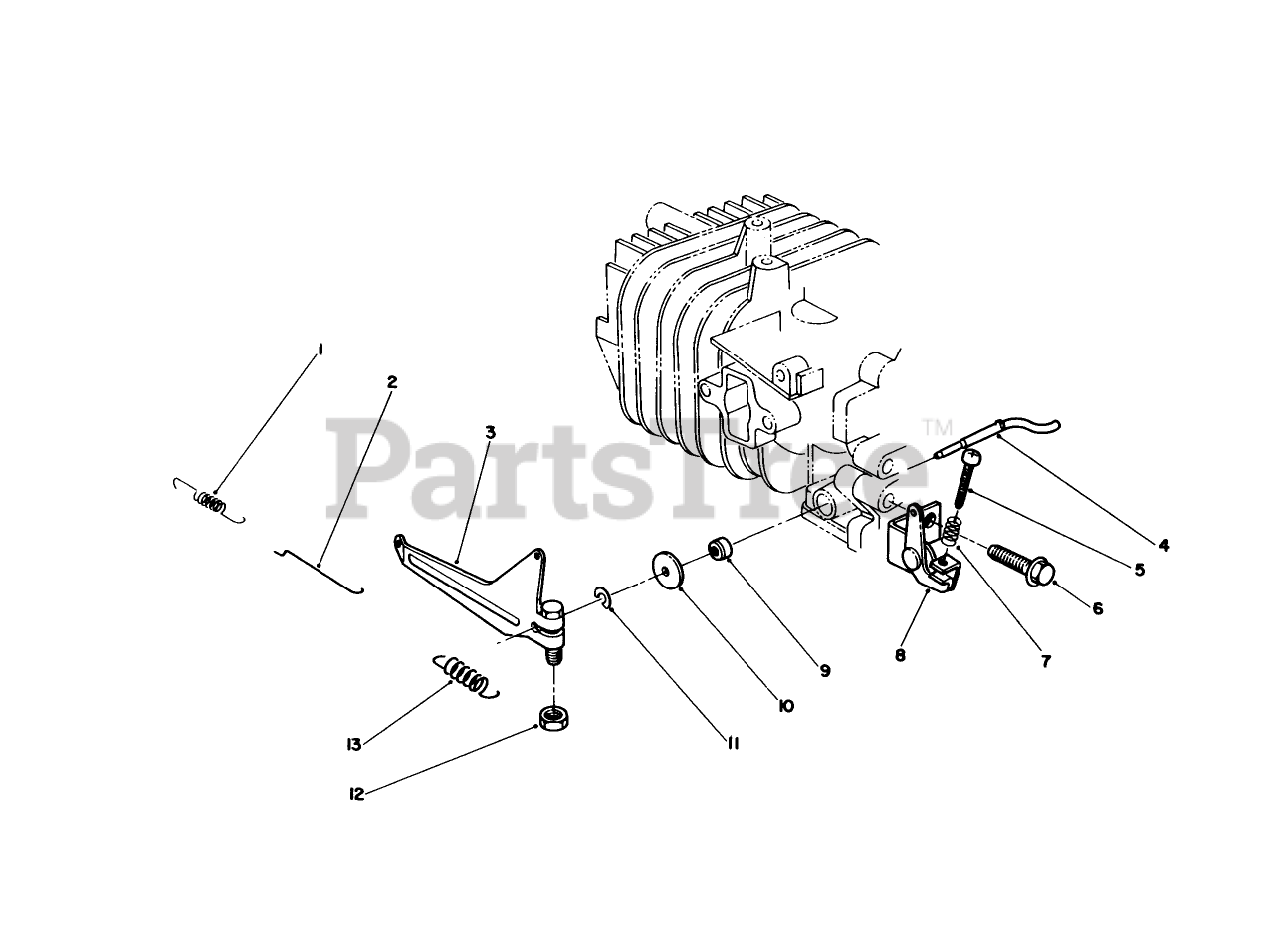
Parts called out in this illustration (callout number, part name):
2	CARB ROD
4	SHAFT
5	SCREW
7	SPRING
8	GOV SPR BRKT
9	SEAL-OIL
10	WASHER
13	GOV SPRING
